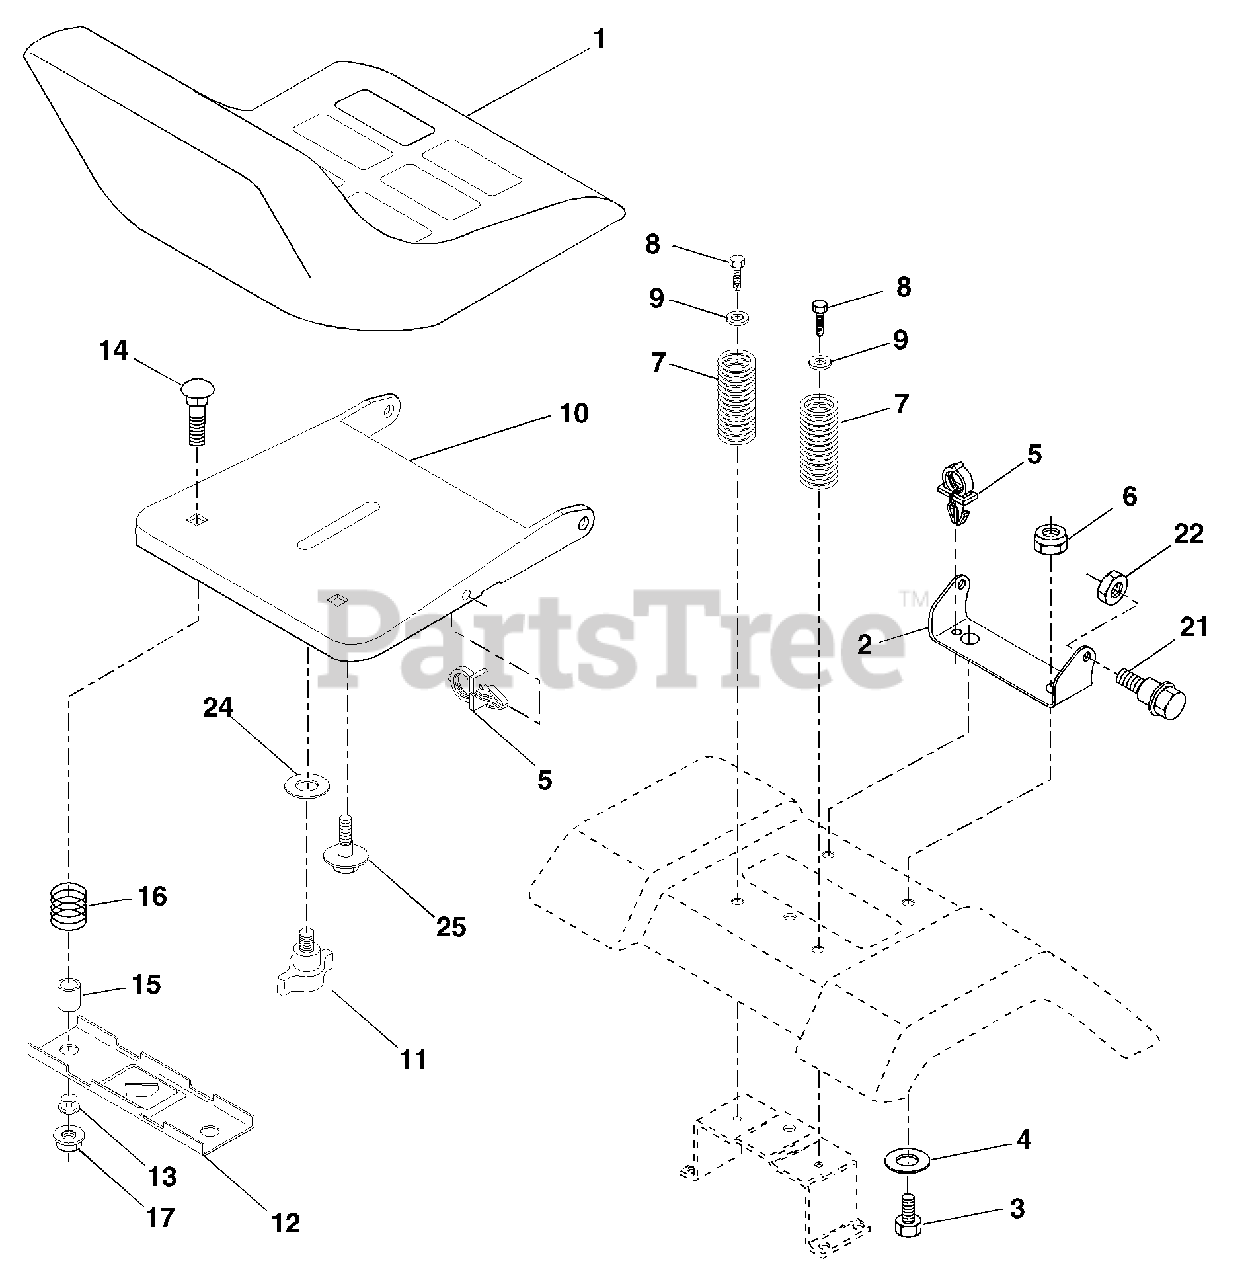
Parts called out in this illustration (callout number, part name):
1	Seat
2	Bracket Pivot Seat 8 720
3	Bolt Fin Hex 3/8-16 x 1
4	Washer Flat 13/32 x 1.0 x 10 Ga.
5	Clip Push-In
6	Nut Hex w/Ins. 3/8-16 Unc
7	Spring Seat Cprsn 2 250 Blk Zi
8	Screw 3/8-16 x 1
9	Washer 13/32 x 1.0 x 14 Ga.
10	Pan Seat
11	Knob Seat Adj Wingnut
12	Bracket Mounting Switch
13	Bushing Snap Blk Nyl 50 Id
14	Bolt Rdhd Sqnk 1/4-20x1-1/2
15	Spacer Split 28 x .88 Zinc
16	Spring Cprsn Plate
17	Nut Lock 1/4 Lge Flg Gr 5 Zinc
21	Bolt Shoulder 5/16-18 Unc
22	Nut Hex Lock W/Ins 5/16-18
24	Washer 17/32 X 1 -3/16 X 12 Ga.
25	Bolt Shoulder 5/16-18 X 62
